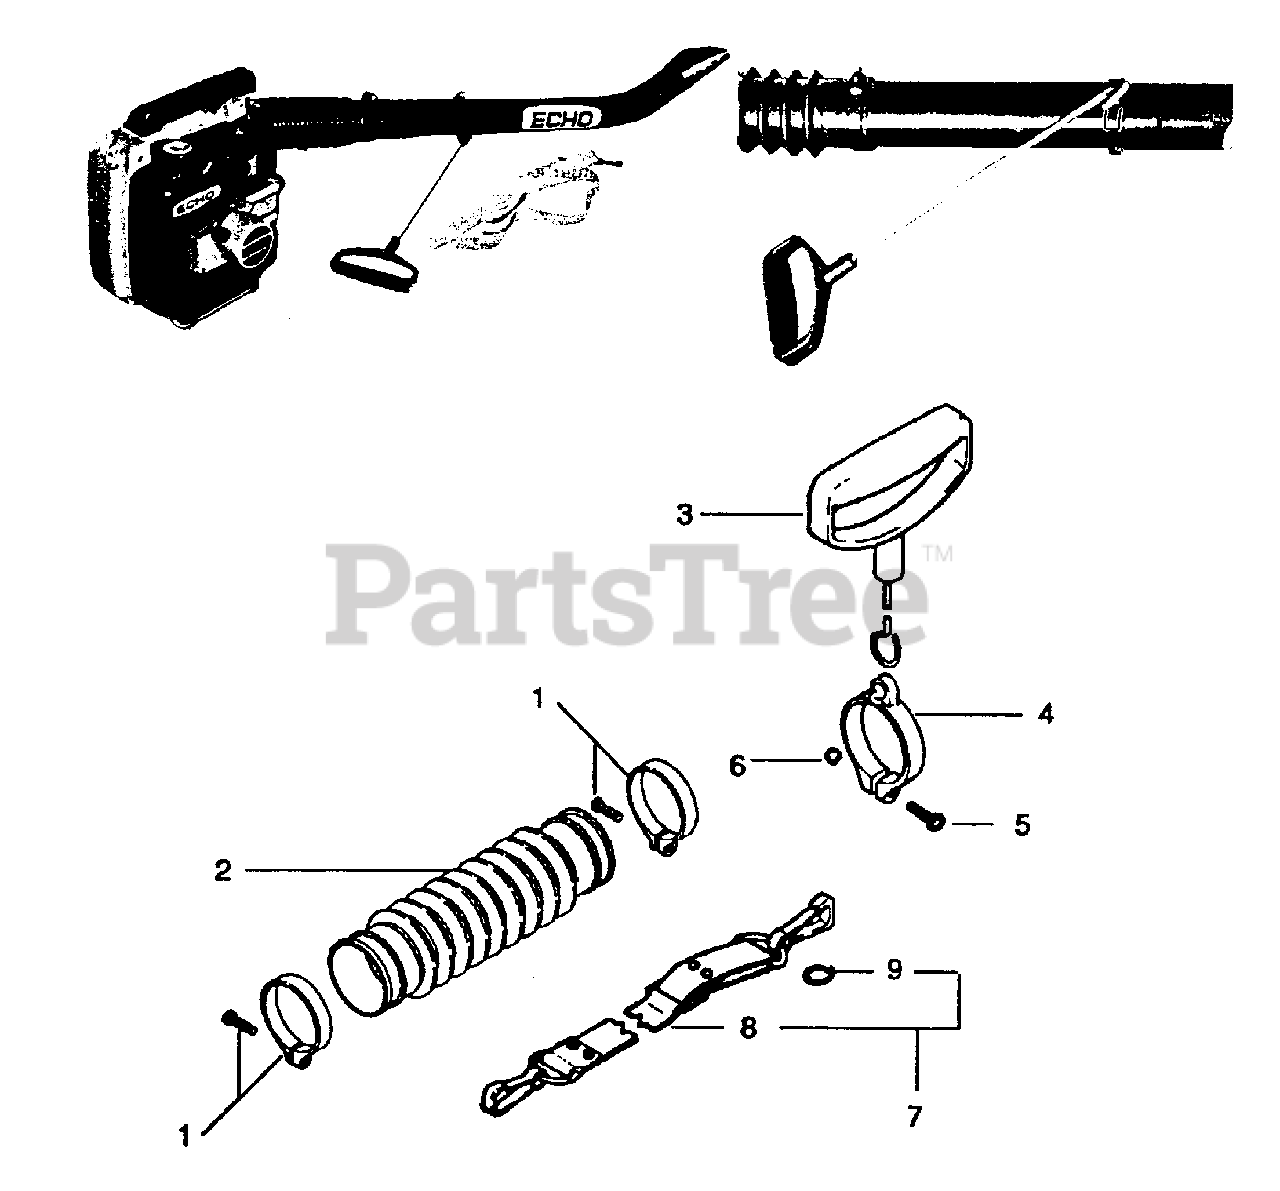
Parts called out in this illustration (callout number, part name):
1	CLAMP KIT
2	TUBE, BLOWER - FLEXIBLE
3	HANDLE
4	CLAMP, HANDLE
5	SCREW 5×25
6	NUT M5
7	SHOULDER STRAP ASSY
9	RING
